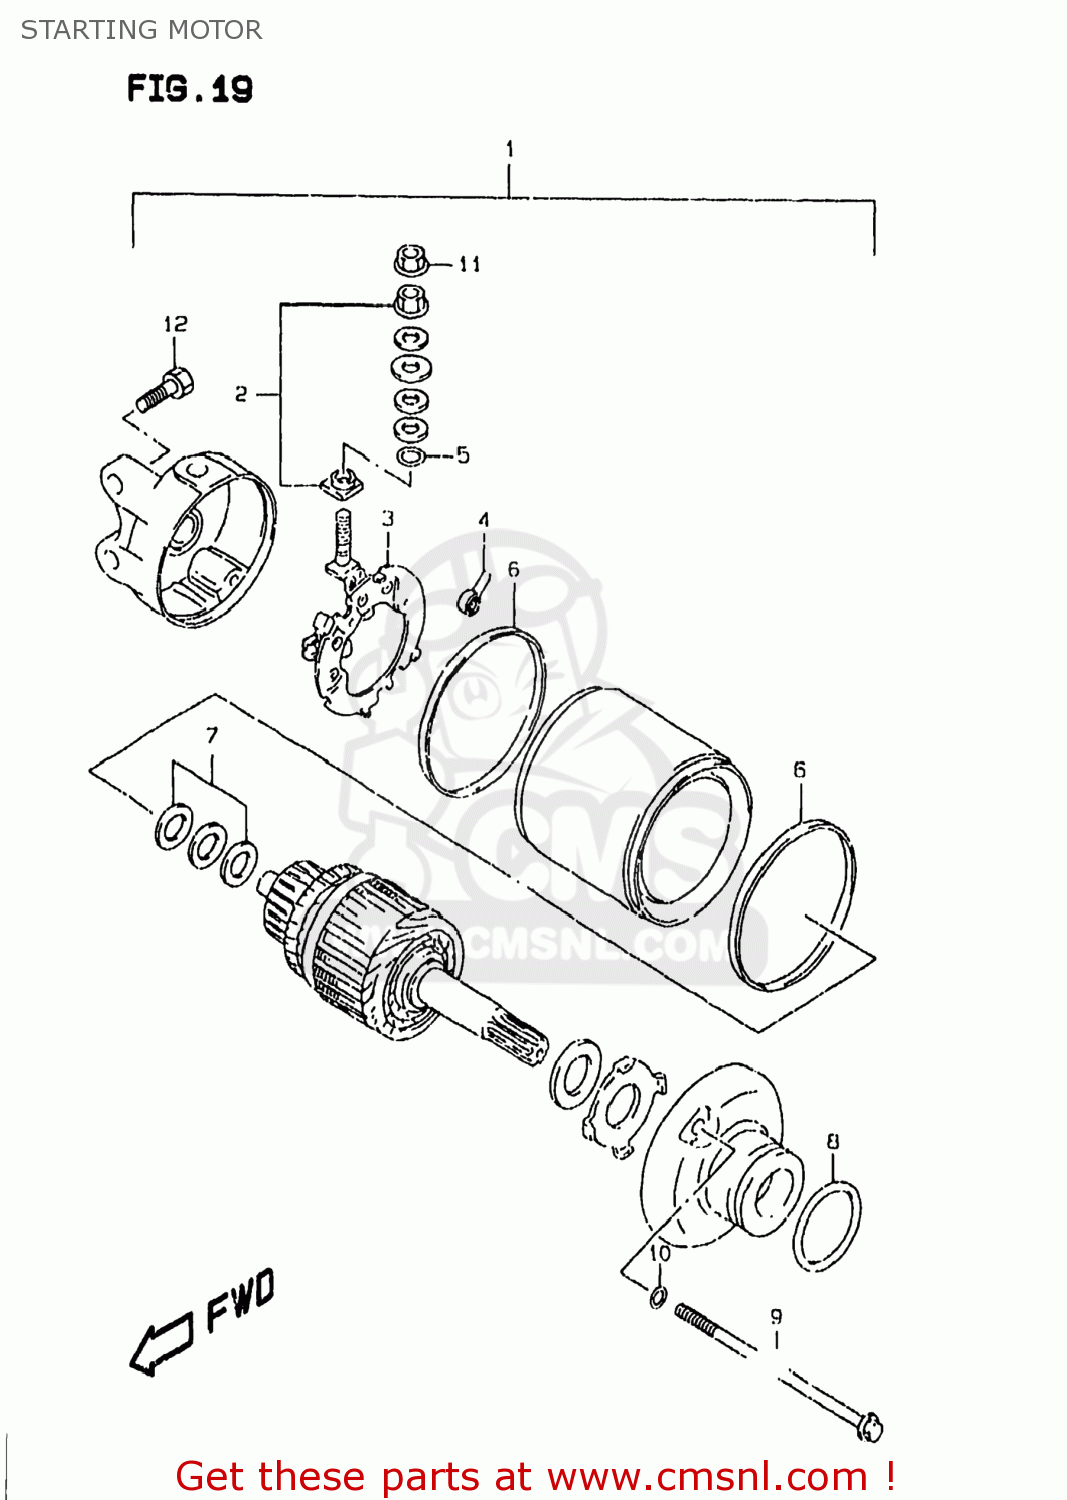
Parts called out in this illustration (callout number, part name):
1	MOTOR ASSY,STARTING
2	BRUSH TERMINAL SET
3	BRUSH HOLDER SET
4	SPRING,BRUSH
5	O RING
6	O RING
7	SHIM SET,STARTING MOTOR
8	O RING(D:3,ID:24.5)
9	SET,BOLT ASSY
10	O RING
11	NUT
12	BOLT
